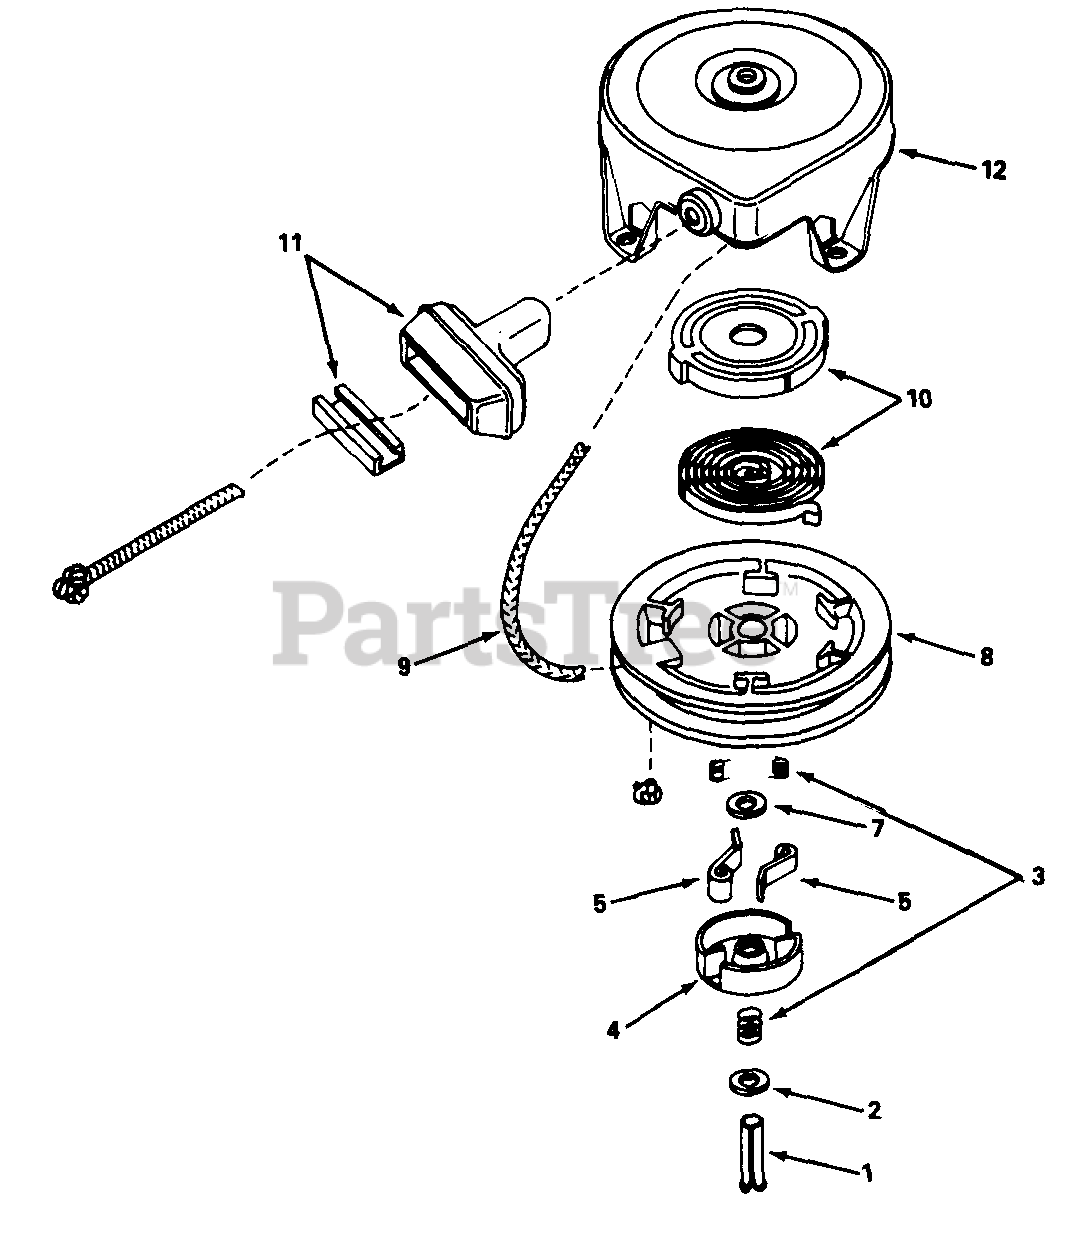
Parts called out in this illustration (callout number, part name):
1	Pin, Spring
3	Spring Ass'y., Brake & Dog
5	Dog, Starter
9	Rope, Starter
10	Spring & Keeper Ass'y.
11	Handle Ass'y., Starter
12	Housing Ass'y., Starter
